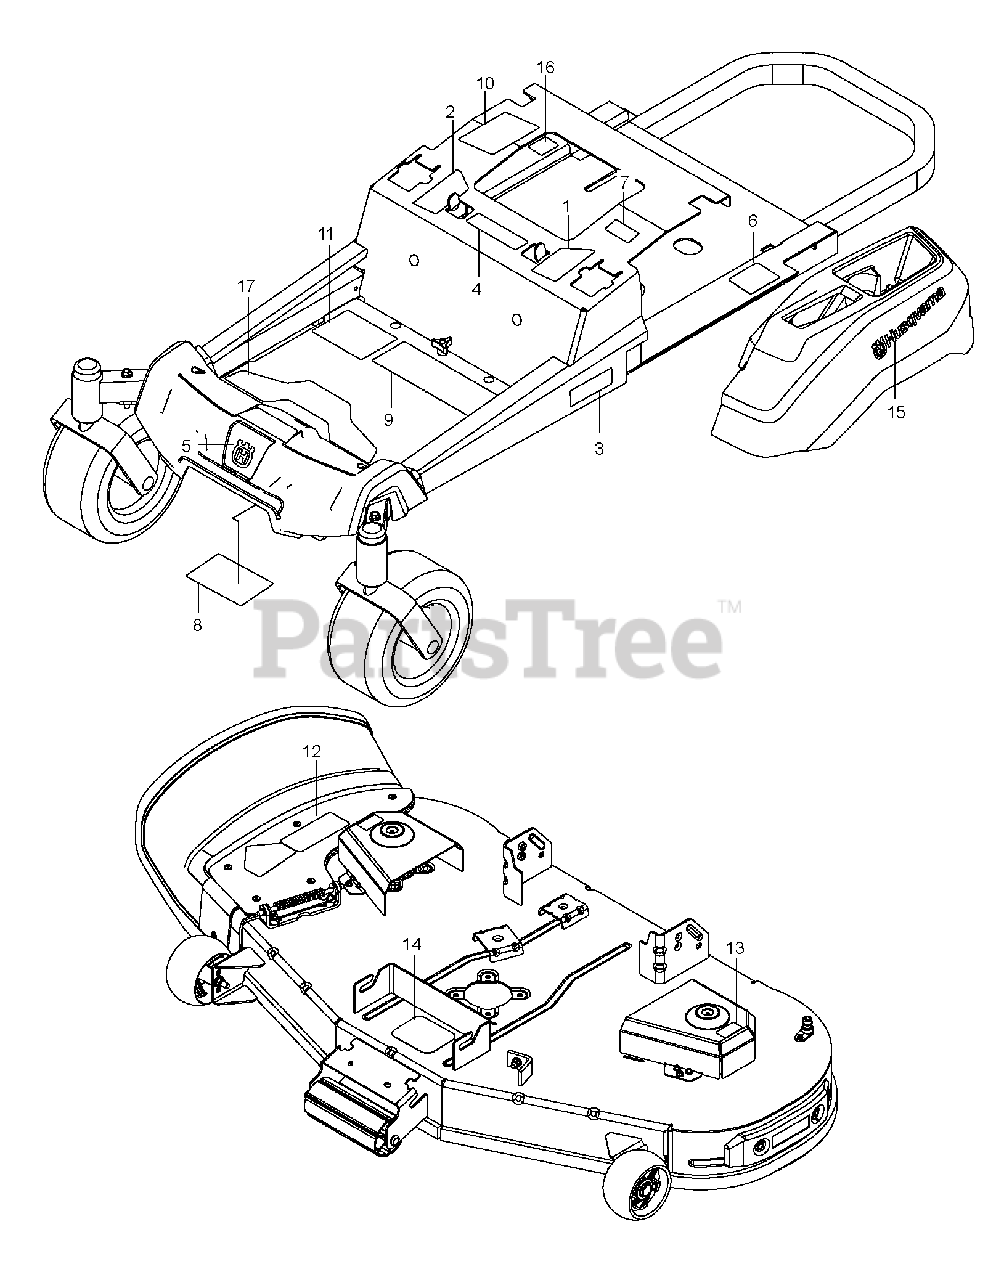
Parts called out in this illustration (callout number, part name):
1	DECAL.ZTR.RZ.THRTL/PRKBRK.V2.L
2	DECAL.ZTR.RZ.THRTL/PRKBRK.V2.R
3	DECAL.MOD/SER.ANSI/OPEI.EN/FR
4	EURO DECAL-BATTERY WARNIN6
5	DECAL.BADGE.55MM.CROWNH.HUSQ
6	DECAL, DO NOT TOW
7	DECAL, EXITING MOWER
8	DECAL, SERVICE
9	DECAL.ZTR.WARNING.SMARTIGNITIN
10	DECAL.WARNING.CUST.RESP.E85.
11	DECAL ZTR STARTING
12	DECAL.TRACT/ZTR.DECKWARN.HUSQ
13	DECAL.DECK.CLEARCUT.NOSTEP
14	DECAL, BELT ROUTING
15	DECAL.HUSQVARNA.210MM
16	DECAL, WARNING SPARK ARRESTOR
17	PAD.RZ.FOOTREST.PLATE
